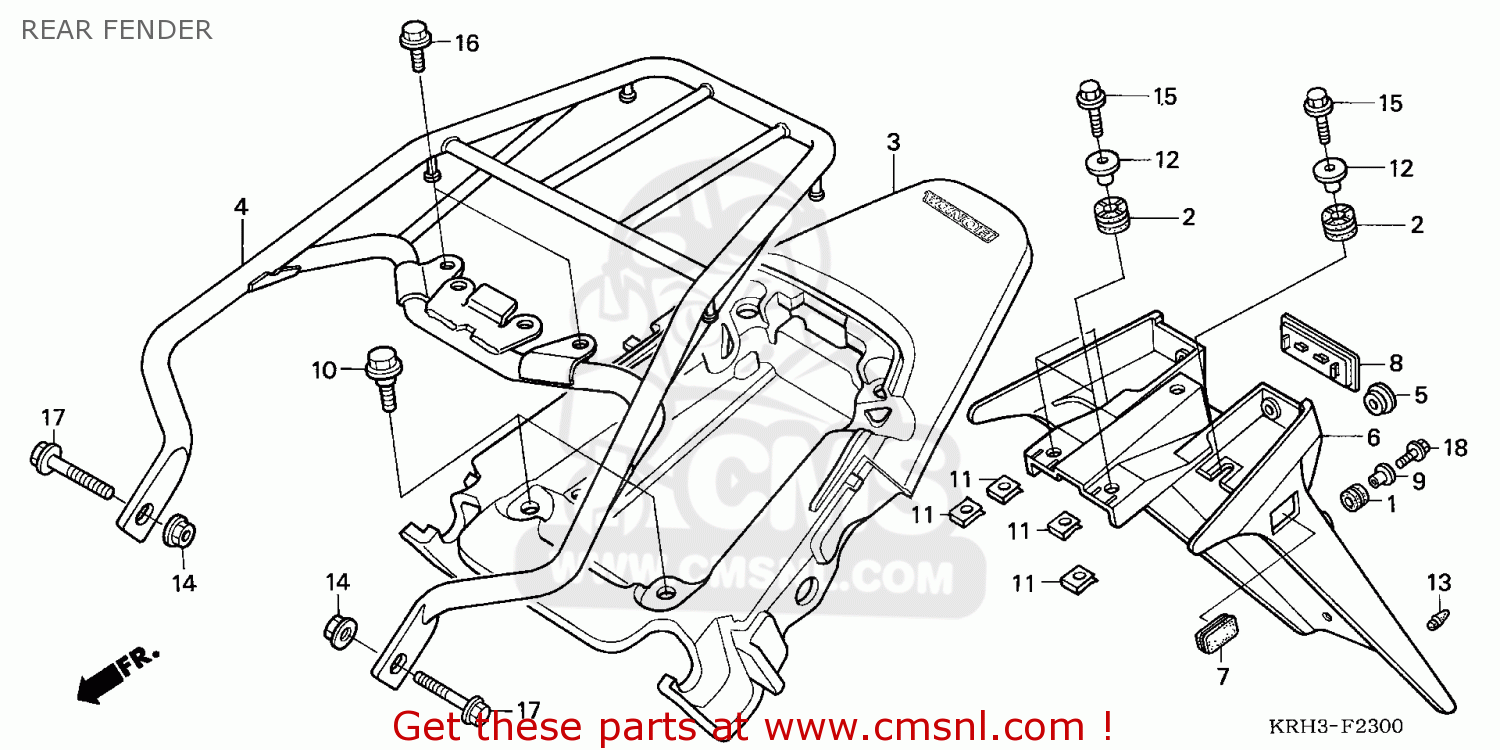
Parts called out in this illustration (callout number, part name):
1	RUBBER,TAILLIGHT
2	RUBBER SPEEDMETER
3	COWL SET, RR. (WL) *
4	CARRIER C*NH262M*
5	GROMMET,SIDECOVER
6	BASE COMP.NUMBER
7	CAP,NUMBER BRKT.
8	CAP,BASE COMP.NUM
9	COLLAR C
10	BOLT,FLANGE,6MM
11	NUT,CLIP 6MM
12	COLLA,19X6.2X13.5
13	PLUG,CORN
15	BOLT,FLANGE,6X22
16	BOLT,FLANGE,8X18
17	BOLT,FLANGE,8X45
18	BOLT,FLANGE,6X18
